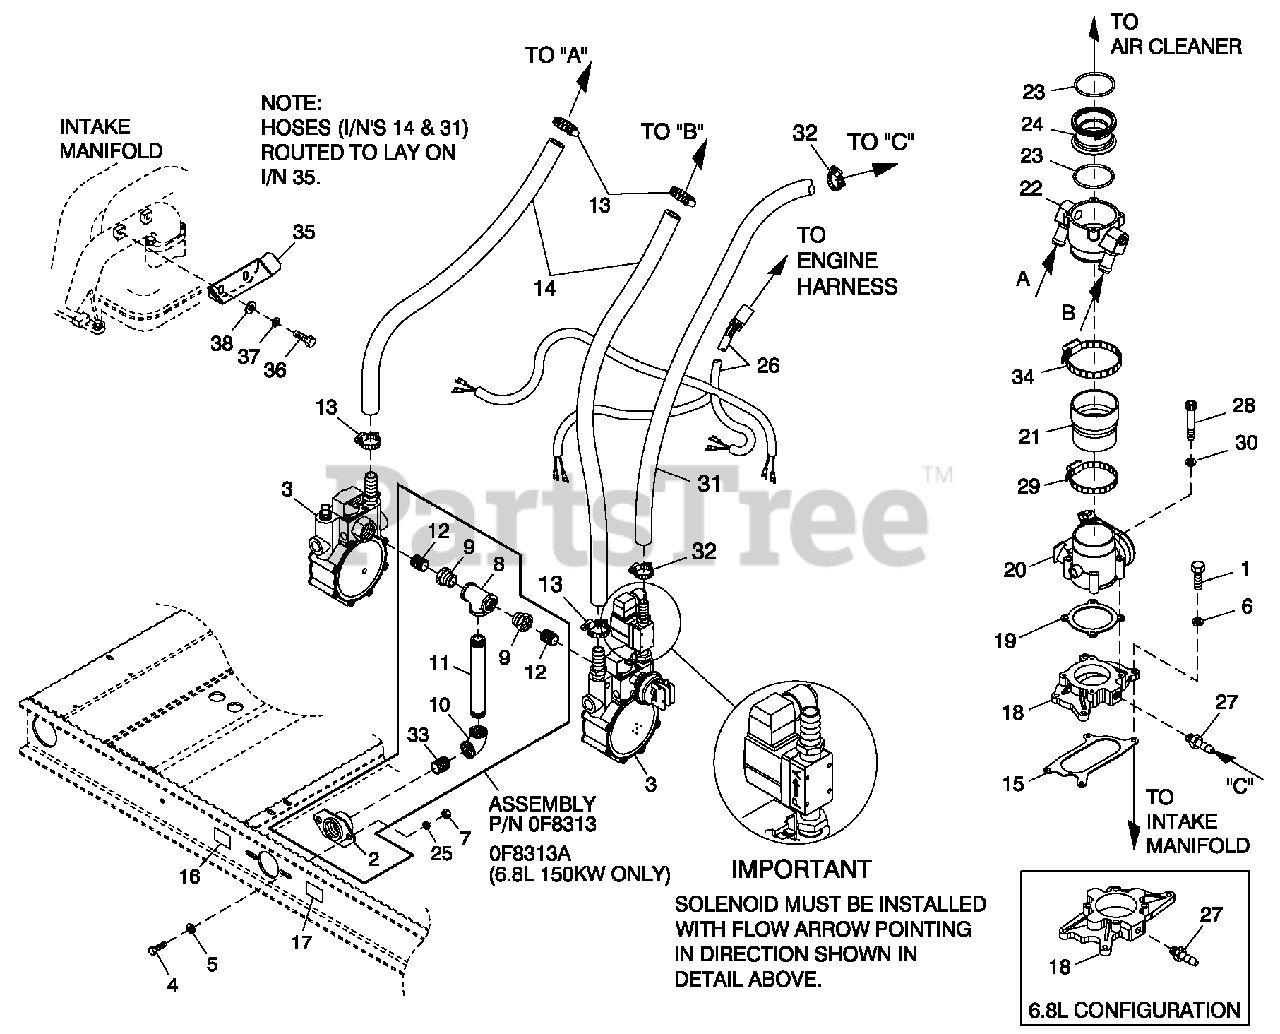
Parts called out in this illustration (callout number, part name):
1	SCREW HHC 5/16-18 X 1-1/4 G5
2	SUPPORT NAT GAS SOLENOID
3	REGULATOR ASSM 5.4L 80KW LPV (5.4L 80KW)
4	SCREW HHC M12-1.75 X 20 G8.8
5	WASHER FLAT 1/2 ZINC
6	WASHER LOCK M8-5/16
7	NUT HEX M12-1.75 G8 YEL CHR
8	PIPE TEE 1-1/4 NPT
9	BSHG RDCR HEX 1-1/4-3/4
10	ELBOW 90D 1-1/4 NPT
11	NIPPLE PIPE 1-1/4 NPT X 3
12	NIPPLE CLOSE 3/4 X 1.375
13	CLAMP HOSE #10 .56-1.06
14	HOSE 3/4 ID SAE-30R2 (45" LG)
15	GASKET ADAPTER THROT BODY
16	DECAL INLET PRESSURE
17	DECAL FUEL INLET LPG (LP VAPOR APPLICATION)
18	ADAPTOR THROTTLE BODY (BOSCH) (6.8L)
19	GASKET GOVERNOR ACTUATOR
20	ACTUATOR BOSCH 60 GOVERNOR
21	REDUCER 3.0" TO 2.75" TURBO
22	MIXER 40/60MM ACTUATOR ASSY
23	O-RING 2-3/4 X 3/32 X 2-15/16
24	VENTURI THROTTLE 36MM (5.4L 80KW)
25	WASHER LOCK 1/2
26	HARNESS FUEL JUMPER DUAL REG
27	BARBED STR 1/4 NPT X 1/2
28	SCREW SHC M6-1.0 X 45 G12.9
29	CLAMP HOSE #44 2.31-3.25
30	WASHER LOCK M6-1/4
31	HOSE 3/8 ID SINGLE BRAID (42" LG)
32	CLAMP HOSE #5.5 .62-.62
33	NIPPLE CLOSE 1.25 NPT X 1.625
34	CLAMP HOSE #52 2.81-3.75
35	BRACKET, HOSE RISER
36	SCREW HHC M6-1.0 X 20 G8.8
37	WASHER LOCK M6-1/4
38	WASHER FLAT M6
